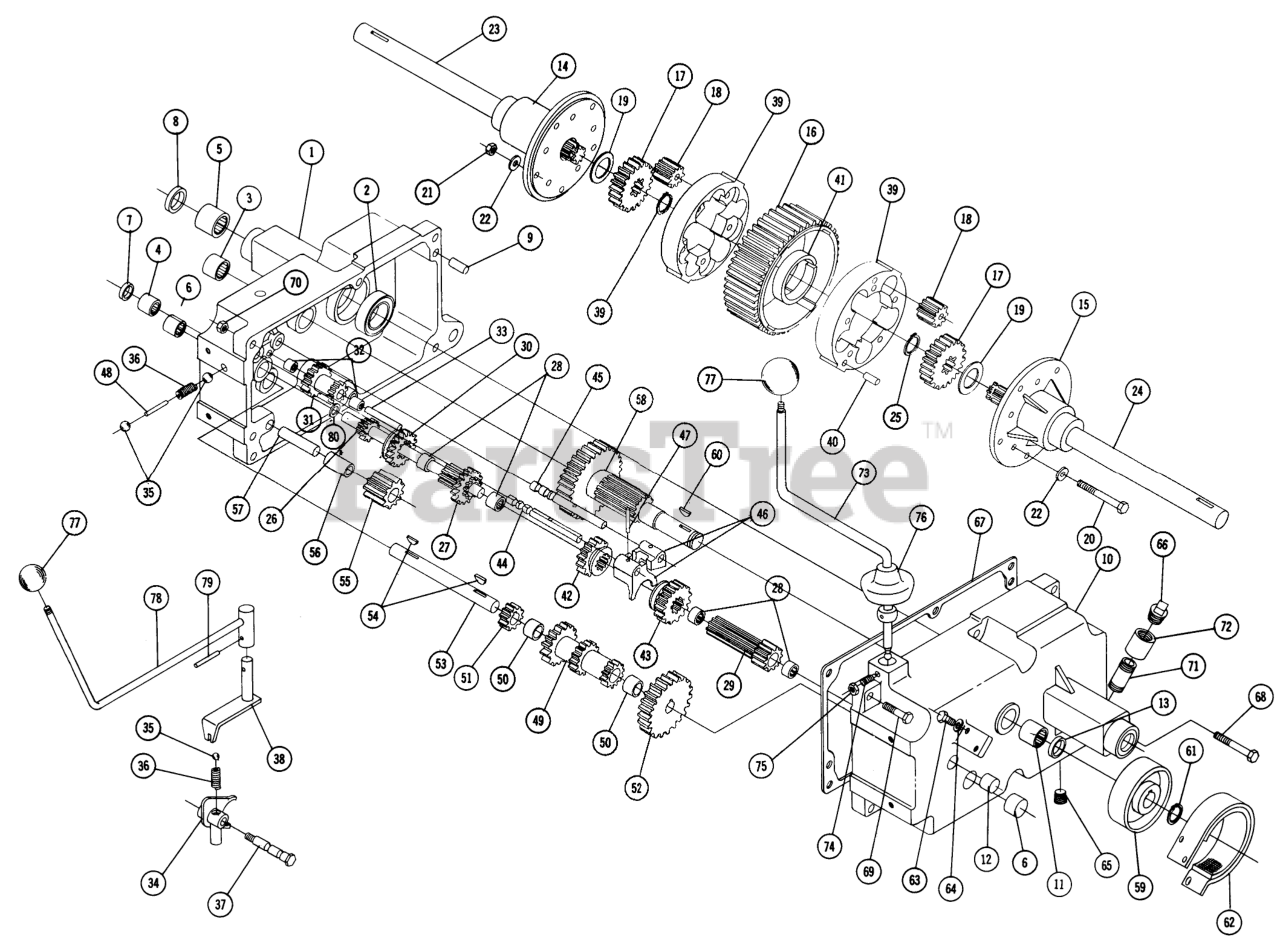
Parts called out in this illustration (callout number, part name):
3	BEARING-NEEDLE
4	BEARING-NEEDLE
6	BEARING-NEEDLE
9	PIN-DOWEL
20	Bolt Hex 3 1/4
21	3/8-16 E.S.
22	Washer
26	SHAFT-INPUT
27	GEAR
28	BEARING-NEEDLE
29	GEAR
30	GEAR-SLIDING
32	BEARING-NEEDLE
33	GEAR-SHAFT REDUCTION
35	BALL-DETENT
37	BOLT-DETENT
38	SHIFT ASM
39	BULLT 252
42	GEAR-HI AND 2ND
43	GEAR-LOW AND REVERSE
44	RAIL-SHIFT
45	RAIL-REAR SHIFT
46	FORK-SHIFT
47	PIN-ROLL
48	PIN-SHIFT
50	BUSHING-BRONZE
52	GEAR-CLUSTER SHAFT
54	Key
55	GEAR/BUSHING ASM-REVERSE IDLER
56	BUSHING
57	PIN-DIFFERENTIAL
60	KEY-WOODRUFF
63	Bolt-1/4-20 x 5/8
64	Lockwasher
67	GASKET-TRANSMISSION
68	Bolt Hex 3/8-16 x 1
69	Bolt, 3/8 16 x 2
72	Coupling 3/8 Pipe
74	SETSCREW
75	Nut 1/4-20
76	COVER-DUST
79	PIN-SPIROL
80	WASHER-THRUST
